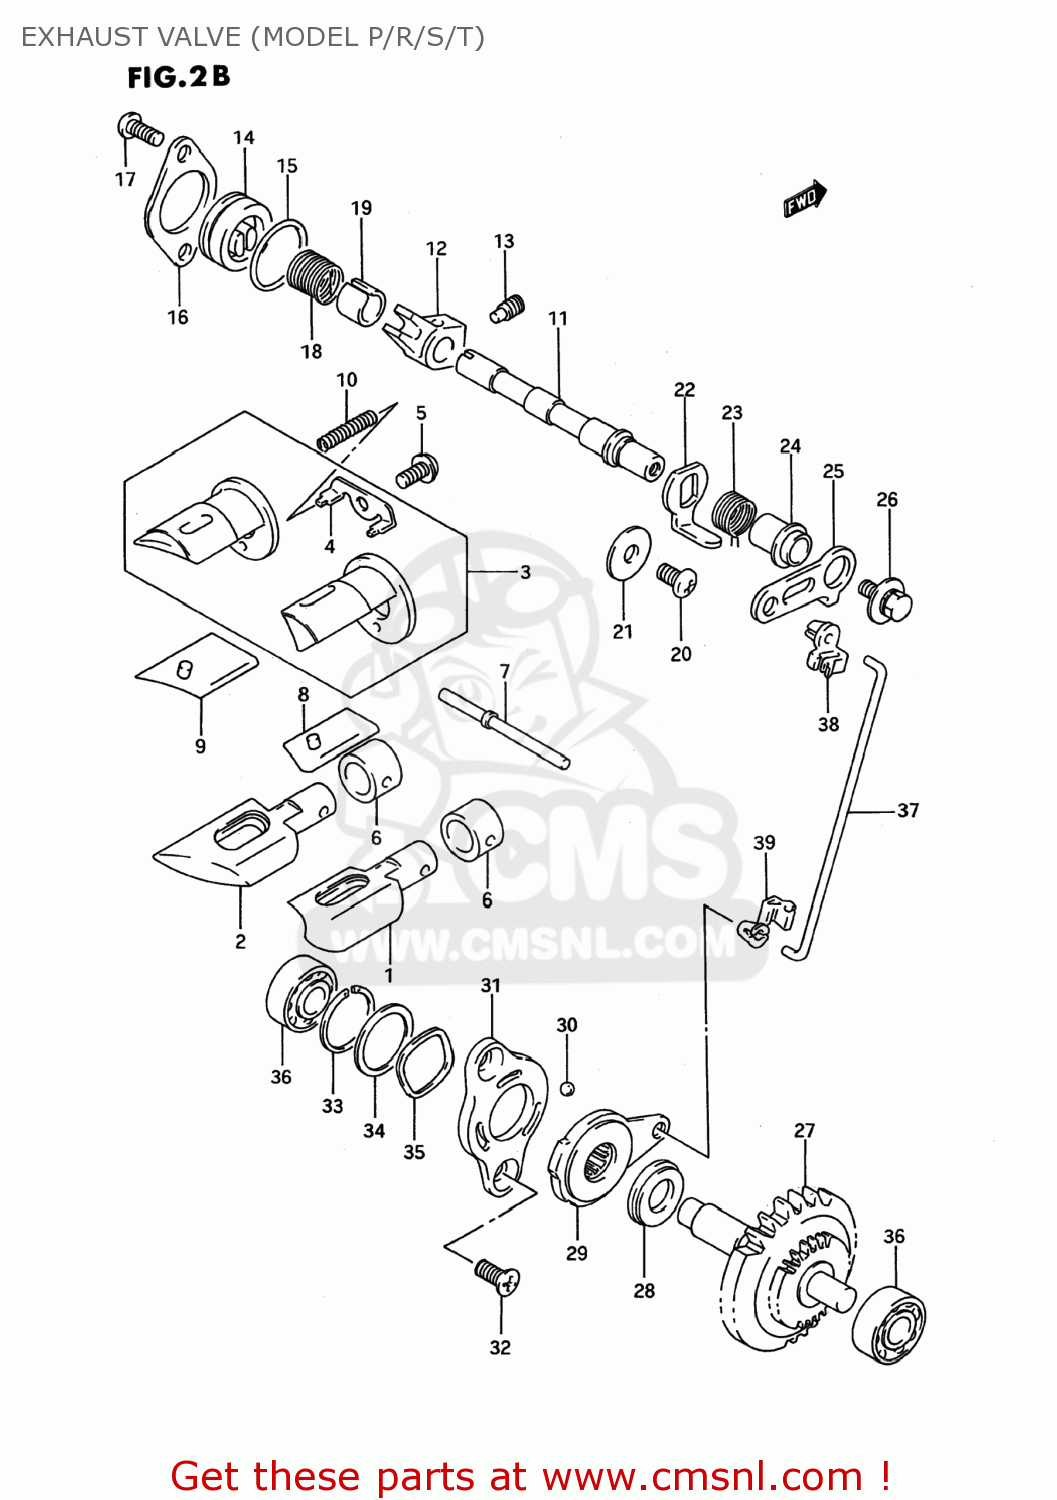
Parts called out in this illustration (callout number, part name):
1	VALVE,EXHAUST,LOWER,RIGHT
2	VALVE,EXHAUST LOW,L
3	GUIDE SET,EXHAUST VALVE
4	STOPPER,EXHAUST VALVE NO.2
5	SCREW
6	SPACER,EXHAUST VALVE
7	PIN,EXHAUST VALVE 48.5MM
8	VALVE,EXHAUST MIDDLE,R
9	VALVE,EXHAUST MIDDLE,L
10	SPRING
11	SHAFT,EXHAUST VALVE
12	ARM,EXHAUST VALVE SHAFT
13	SCREW(6X10)
14	CAP,EXHAUST VALVE
15	O RING(D:1.9,ID:22.6)
16	RETAINER,EXHAUST VALVE
17	SCREW
18	SPRING
19	SPACER,EXHAUST VALVE SPRING
20	BOLT
21	WASHER
22	LEVER,EXHAUST VALVE NO.2
23	SPRING
24	SPACER,EXHAUST VALVE
25	LEVER,EXHAUST VALVE NO.1
26	BOLT(5X12)
27	GOVERNOR ASSEMBLY,EXHAUST
28	BEARING(10X22X2.8)
29	ACTUATOR,EXHAUST VALVE
30	BALL
31	STARTER,EXHAUST VALVE ACTUATOR
32	SCREW(5X10)
33	CIRCLIP
34	SHIM(19.1X25X0.3)
35	WASHER
36	BEARING(8X22X7)
37	ROD,EXHAUST VALVE
38	BUSH,EXHAUST VALVE ROD NO.1
39	BUSH,EXHAUST VALVE ROD NO.2
